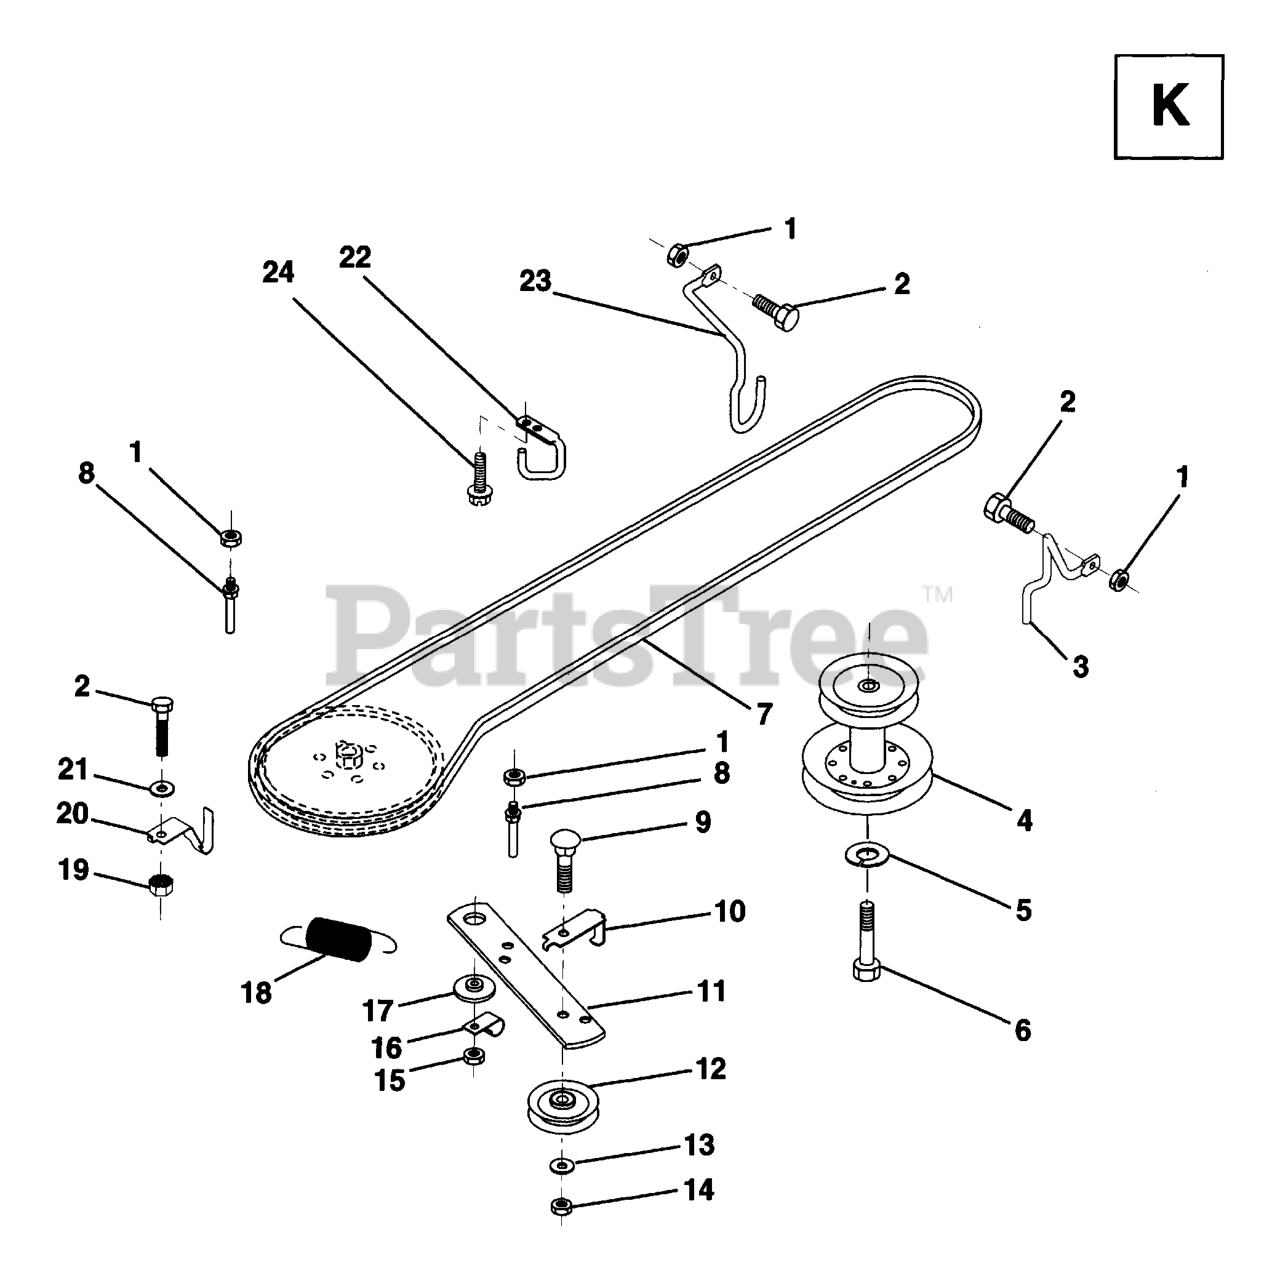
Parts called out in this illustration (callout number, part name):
1	LOCKNUT
2	BOLT
3	KEEPER/MOWER DRIVE RH
4	PULLEY.ENGINE.36/38 LR
5	LOCKWASHER
6	Bolt, Hex Hd. 7/16-20 UNF Grade 5
7	BELT
8	KEEPER,DRIVE BELT
9	Bolt, Carriage 3/8-16 UNC x 1-1/2
10	KEEPER.BELT.GROUND.DRIVE.IDLER
11	ARM/GROUND DRIVE CLUTCH
12	PULLEY.IDLER.FLAT
13	WASHER
14	LOCKNUT
16	CLIP,INSULATOR
17	SPACER RETAINER
18	SPRING.EXTENSION
19	NUT
20	KEEPER-T/A GROUND DRIVE BELT
21	Washer 11/32 x 5/8 x 16 Ga SD
22	KEEPER,FRA DR BEL
23	KEEPER-MOWER DRIVE LH
24	SCREW
